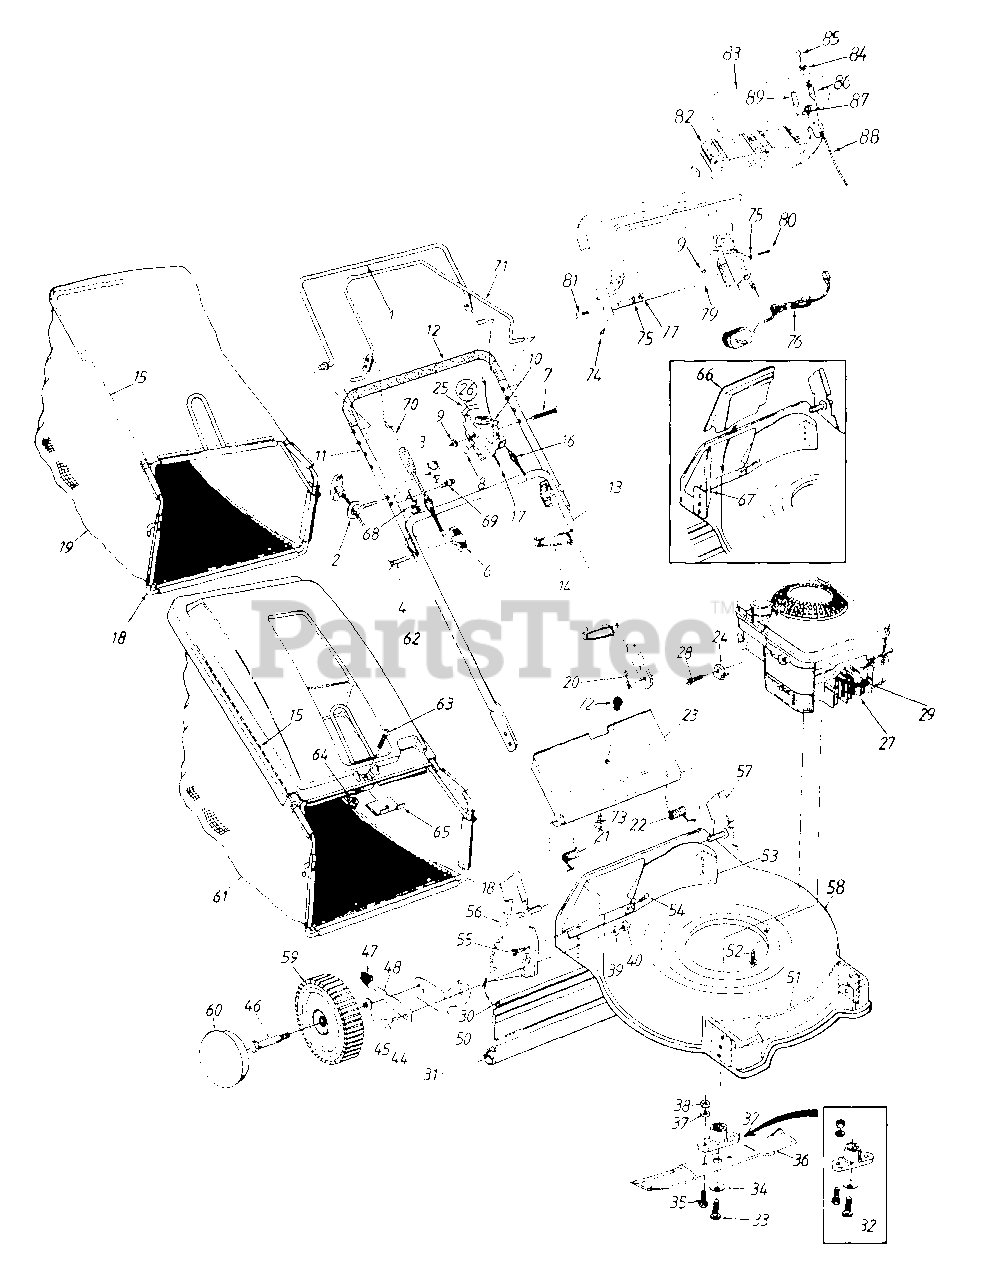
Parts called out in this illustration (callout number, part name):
2	Rope Guide
3	Handle Knob 1/4-20 Thd.
4	Curved Hd. Bolt 5/16-18 x 2" Lg.
6	Hand Knob
7	Oval C-Sunk Mach. Scr.
8	Spr. Wash. .66" I.D.
9	Hex L-Nut 1/4-20 Thd.
10	Throttle Lever
14	Cable Tie
16	Control Cable - 36" For model (448, 454, 456, 454, 458)
16	Control Cable - 51" For model (455)
17	Throttle Control Wire - 42" For model (455)
17	Throttle Control Wire - 55" For model (448, 454, 456, 458)
19	Grass Bag (w/Logo)
20	Int. Cotter Pin 5/16" Dia.
21	Door Spring - R.H.
22	Door Spring - L.H.
24	Cable Clamp (B&S)
25	Throttle Body
26	Throttle Box Comp. Incl Ref. 7, 8, 9, 10, 25
27	Engine
28	hex Sems Scr. #10-32 x .38" Lg. For model (455)
28	Hex Wash. Hd. Scr. #10-32 x .62" Lg. (B&S)
29	Spark Plug Boot Optional
30	Wire Rod
31	Rear Flap
32	Blade Adapter Kit
33	Hex Bolt 3/8-24 x 1.5" Lg.
34	Bell-Wash. .39" I.D.
35	Hex Bolt 3/8-24 x 1" Lg.
36	21" Blade
36	21" Mulching Blade Optional
37	L-Wash. 3/8" I.D.
38	Hex Nut 3/8-24 Thd.
39	Bell-Wash. .39" I.D. x 1.38"
40	Hex Nut 3/8-16 Thd.
44	Shld. Bolt .5" Dia. x .357"
45	Bell-Wash. .38" I.D. x .88" O.D.
46	Axle Bolt
47	Spring Lever Knob
48	Spring Lever
50	Pivot Bar
54	Torx Mach. AB-Tap Scr. 1/4 x .62" Lg.
55	Hex L-Wash. Hd. AB-Tap Scr. 1/4 x .62" Lg.
56	Handle Brkt. Ass'y. - R.H.
57	Handle Brkt. Ass'y. - L.H.
60	Hub Cap 3-1/2" Dia. Gray Optional
60	Hub Cap 5-1/2" Dia. Gray Optional
60	Hub Cap 5-1/2" Dia. Beige Optional
61	Grass Bag
62	Hard Top Cover
63	Pan Hd. Mach. Scr. 1/4-20 x .5" Lg.
64	Hex Nylon L-Nut 1/4-20 Thd.
68	Cable Mtg. Brkt.
69	Hex Wash. AB-Tap Scr. 5/16" x .75" Lg.
70	S.P. Cable 44.75" Lg.
73	Truss Mach. Scr. #10-24 x .38" Lg.
74	Pan Hd. Scr. #12 x 3/4" Lg.
75	Bell-Wash. 1/4" I.D.
76	Charger
77	Hex Nut 1/4-20 Thd.
78	L-Wash. 1/4" I.D.
81	Curved Hd. Bolt 1/4-20 x 1.25" Lg.
82	Battery Pack
83	Upper Battery Tray
84	Key Switch
85	Key
86	Fuse Holder
87	Plug
88	Harness
89	Fuse 7-1/2 Amp.
